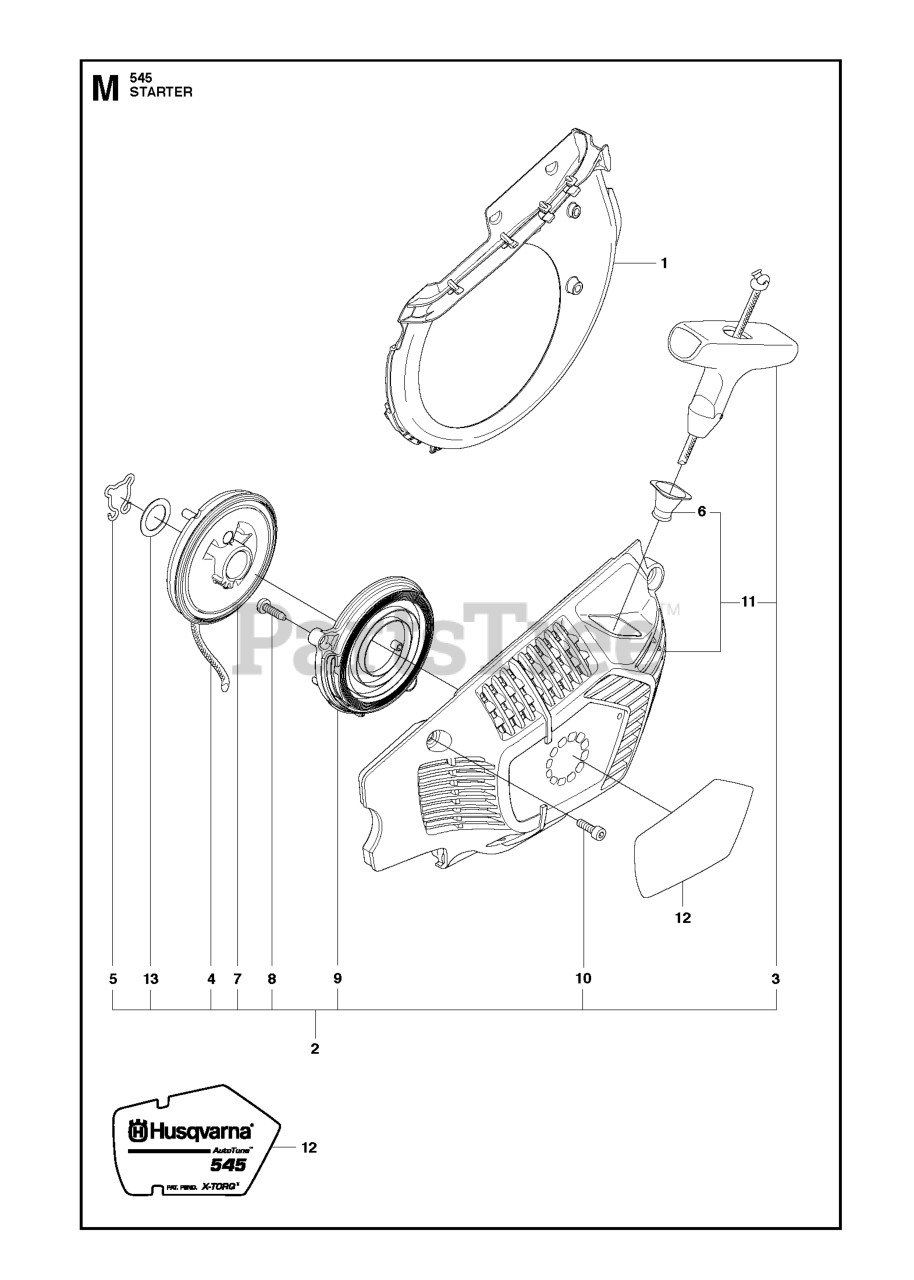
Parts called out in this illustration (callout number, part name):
1	COOLING AIR CONDUCTOR
2	STARTER ASSY
3	HANDLE
4	STARTER ROPE
5	CLIPS
6	SLEEVE
7	STARTER PULLEY ASSY
8	SCREW
9	SPRING CASSETTE ASSY
10	SCREW.CIHPANMO M5X19 10.9
11	STARTER HOUSING
13	WASHER
